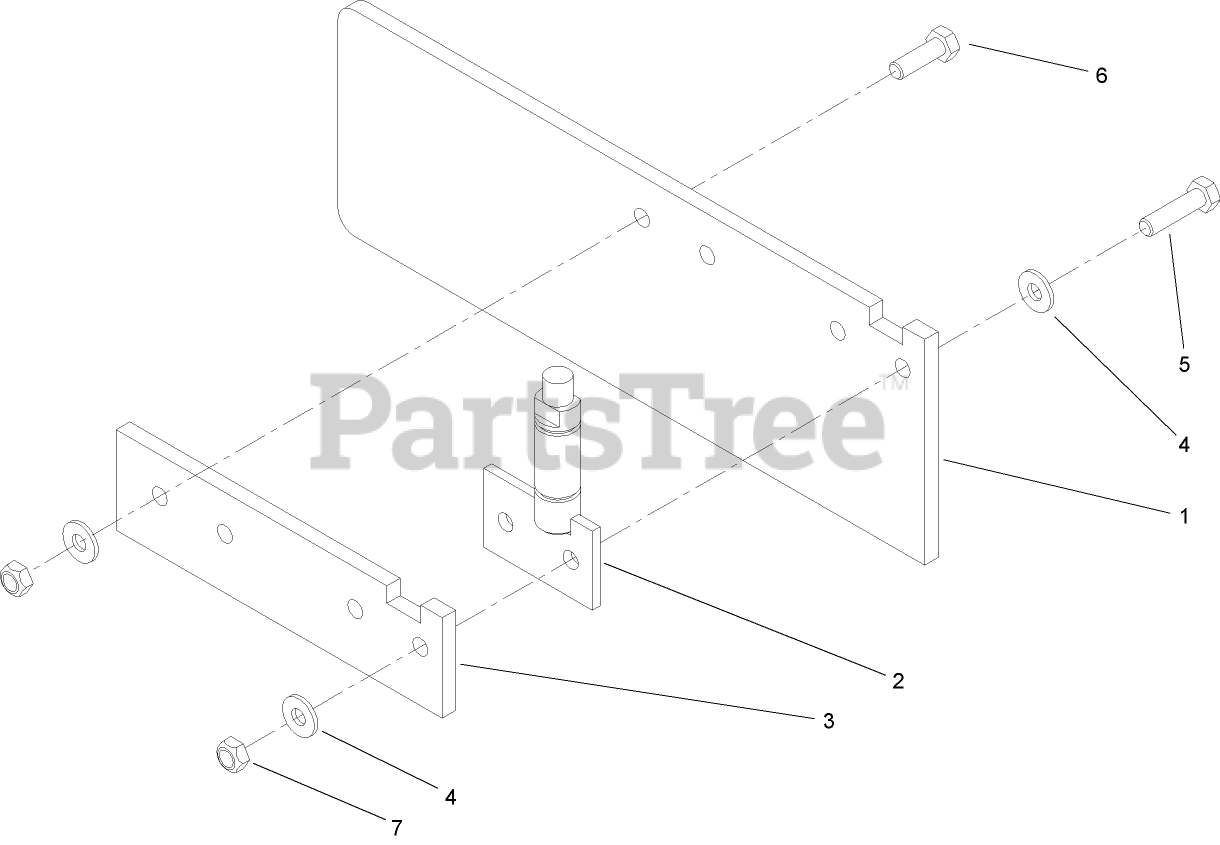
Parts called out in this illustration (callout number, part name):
1	GATE-CHUTE, RUBBER
2	HINGE-GATE
3	DOOR-SUPPORT
4	WASHER-FLAT
5	SCREW-HH
6	SCREW-HH
7	NUT-LOCK, NI
